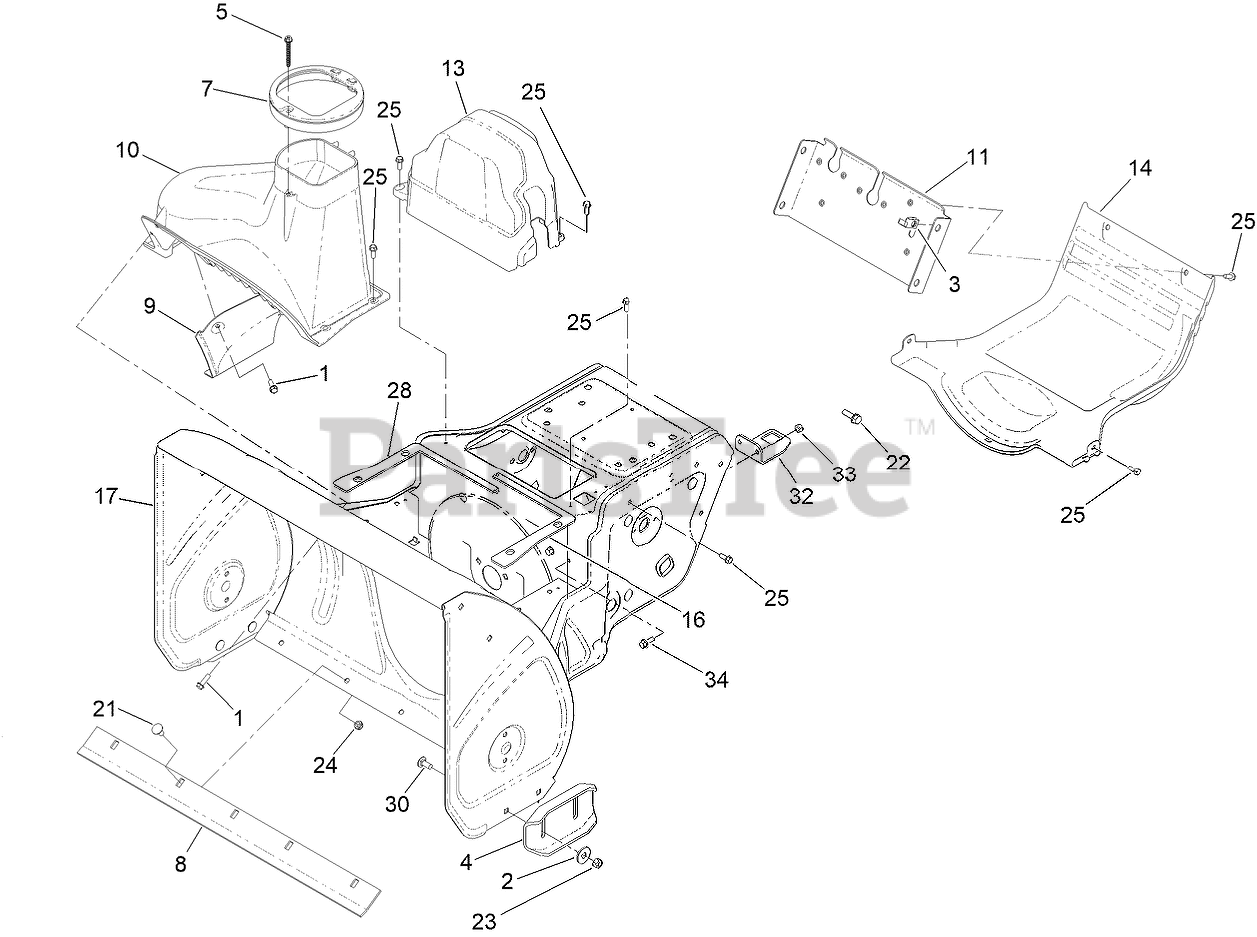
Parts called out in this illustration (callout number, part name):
1	SCREW-HWH
2	WASHER
3	NUT-U
5	SCREW-HWH, PLASTITE
7	GUIDE-CHUTE
8	SCRAPER-26 INCH
9	COVER-LINER
11	BRACE-FRAME
13	COVER-BELT
14	COVER-LOWER
16	SEAL-HOUSING, LH
17	FRAME ASM
21	SCREW-CARR
22	SCREW-HHF
23	NUT-LOCK, NI
24	NUT-LOCK, NI
25	SCREW-HWH
28	SEAL-HOUSING, RH
30	SCREW-CARR
32	BRACKET-POST, CHUTE
33	SCREW-HHF
34	NUT-HEX
